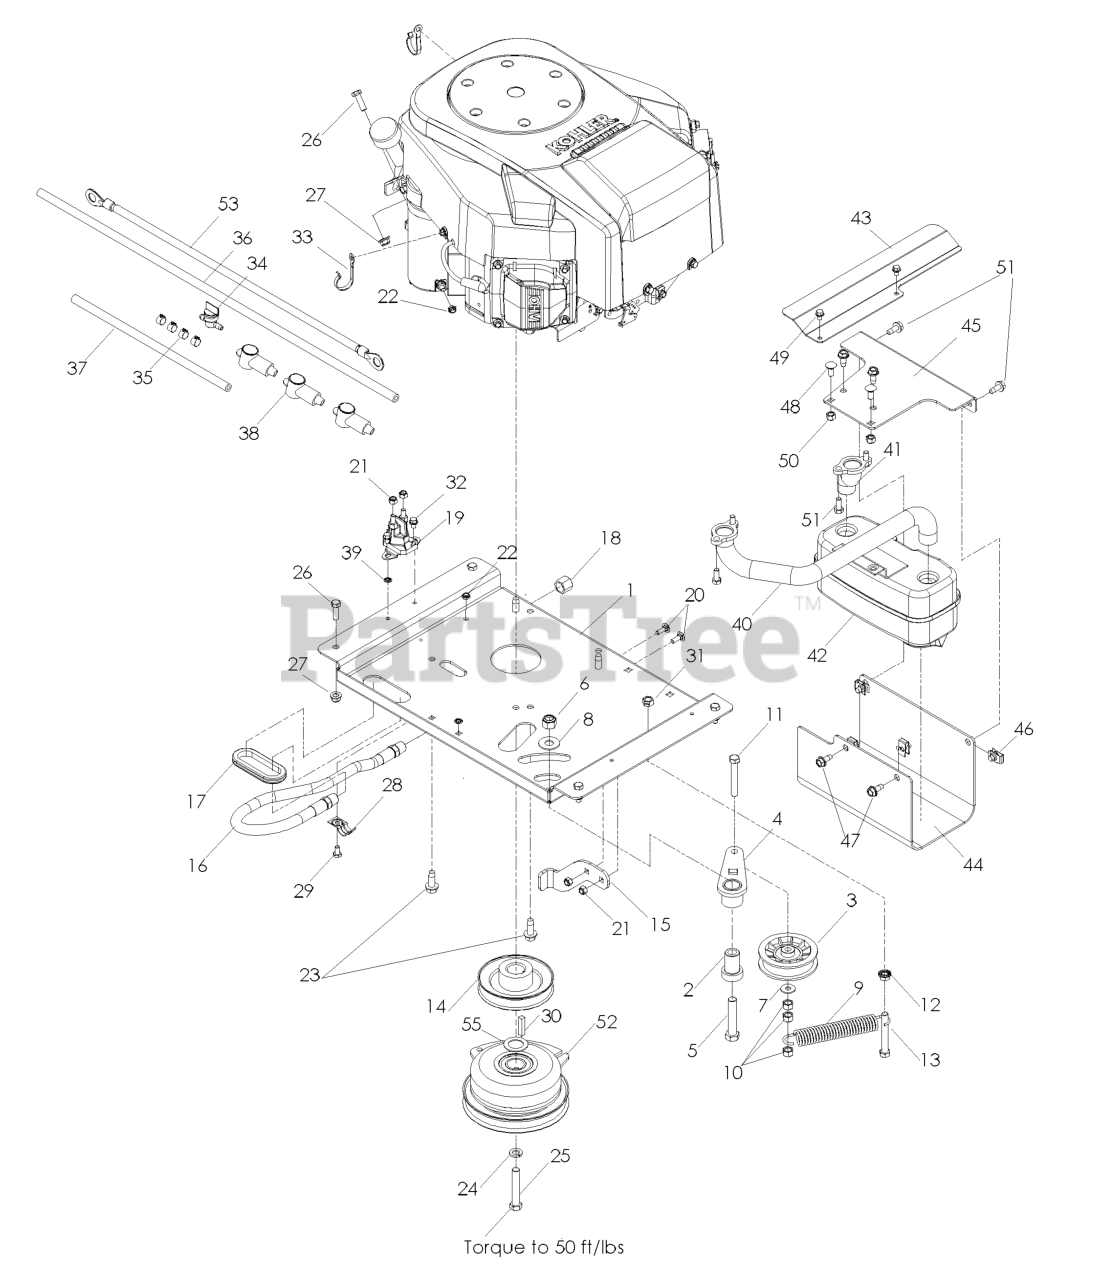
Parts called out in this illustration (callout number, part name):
1	PLATE, ENGINE
2	IDLER SPINDLE
3	PULLEY, IDLER RAKE & ZTR
4	RP.IDLER ARM WELDMENT
5	HEX SCREW 1/2-13 X 2.5" GR 5
6	NUT 1/2-13 HEX NYLOC ZD
7	WASHER 5/16 FLAT
8	WASHER 1/2 FLAT
10	NUT 3/8-16 NYLOC
11	HCS 3/8-16 X 2-1/2 TPBLT
12	NUT 3/8C WHIZ
13	SCREW 3/8C X 2 3/4 HEX CAP
15	TIE DOWN, CLUTCH
16	DRAIN, OIL
20	RHSNB 1/4C X 3/4
21	NUT.1/4-20.HEX.NYLOC.ZD
22	JAM NUT 1/4C (2 2 PW01)
23	HHFS 3/8-16 X 1.0 THD FORMING
24	WASHER 7/16 LOCK
25	BOLT 7/16F X 2 1/2
26	HCS 5/16C X 1
27	5/16-18 NYLOC FLANGE NUT
29	HCS 1/4-20.
30	KEY, 1/4 SQ X 1 1/4
31	NUT 3/8C CENTERBLOCK
32	HWST 1/4C X 3/8
34	FUEL VALVE
35	HOSE CLAMP
36	FUEL LINE 30"
37	FUEL LINE 13"
39	WASHER 1/4 INT TOOTH
40	MANIFOLD, FT
41	MANIFOLD, RR
42	MUFFLER ASM TWIN
43	SHIELD, HEAT
44	GUARD, MUFFLER
45	MOUNT MUFFLER BLACK
46	U-CLIP 5/16-18 NUT RETAINER
47	BOLT 5/16-18 X 3/4
48	BOLT 5/16C X 3/4" CARRIAGE
49	HWST 1/4C X 3/8
50	NUT 5/16 NYLOC
51	HCS 5/16C X 3/4
52	CLUTCH, 125 FT/LB
53	CLUTCH, 200 FT/LB
54	CABLE, POSITIVE
55	WASHER, 1.025 ID X 1.64
